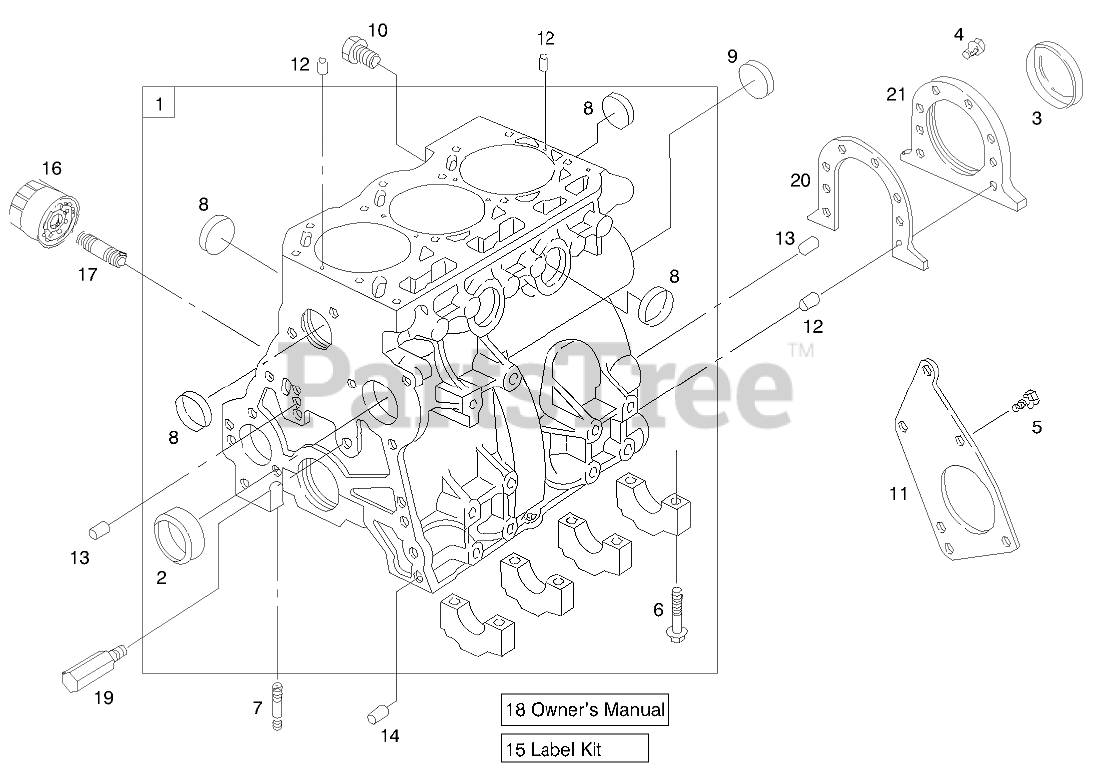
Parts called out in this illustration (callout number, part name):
1	CYLINDER ASSEMBLY
1	HEAD-CYLINDER
2	BUSHING
3	SEAL-OIL
4	SCREW-HEX
5	SCREW-HEX
6	SCREW-HEX
7	STUD-METRIC
8	PLUG-WELCH
8	SWITCH-TEMPERATURE, WATER
9	PLUG-WELCH
9	GASKET-SET
10	PLUG (CYLINDER BLOCK)
11	BRACKET-MOUNTING
12	PIN-LOCATING
13	PIN-LOCATING
14	PIN-LOCATING
14	KIT-VALVE OVERHAUL
15	LABEL KIT
15	SHAFT-GEAR
16	FILTER-OIL
17	ADAPTER-FILTER, OIL
18	MANUAL-OWNERS
19	NOZZLE-OIL
20	GASKET-RETAINER
21	RETAINER-SEAL
